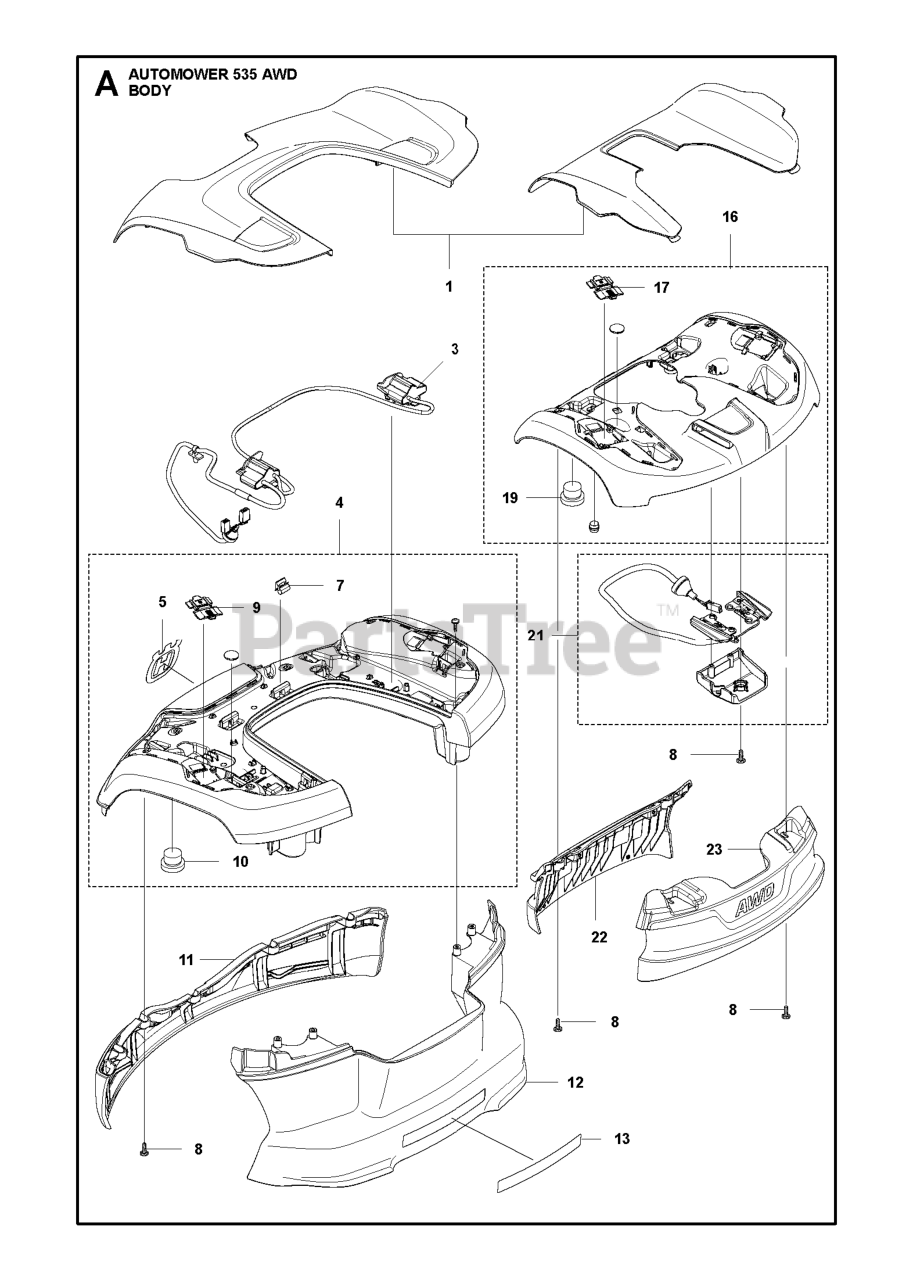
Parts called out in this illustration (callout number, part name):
3	Wires
4	Body
5	Decals
7	Clips
8	SCREW ITXPANT
9	Holders
10	CAP SNAPLOC
11	Bumpers
12	Bumpers
13	LABEL WARNING P15
16	Body
17	Holders
19	CAP SNAPLOC
22	Bumpers
23	Bumpers
